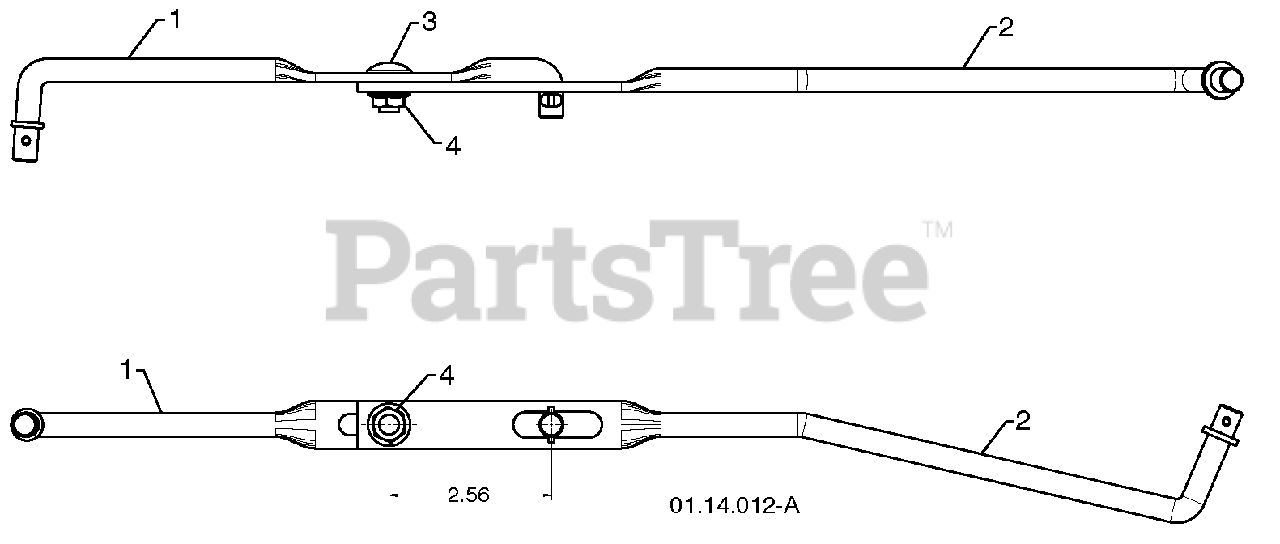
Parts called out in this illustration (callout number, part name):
1	SHIFTER ROD TOP
2	SHIFTER ROD BOTTOM
3	CARRIAGE BOLT 5/16-18 X .75
4	NUT 5/16-18
